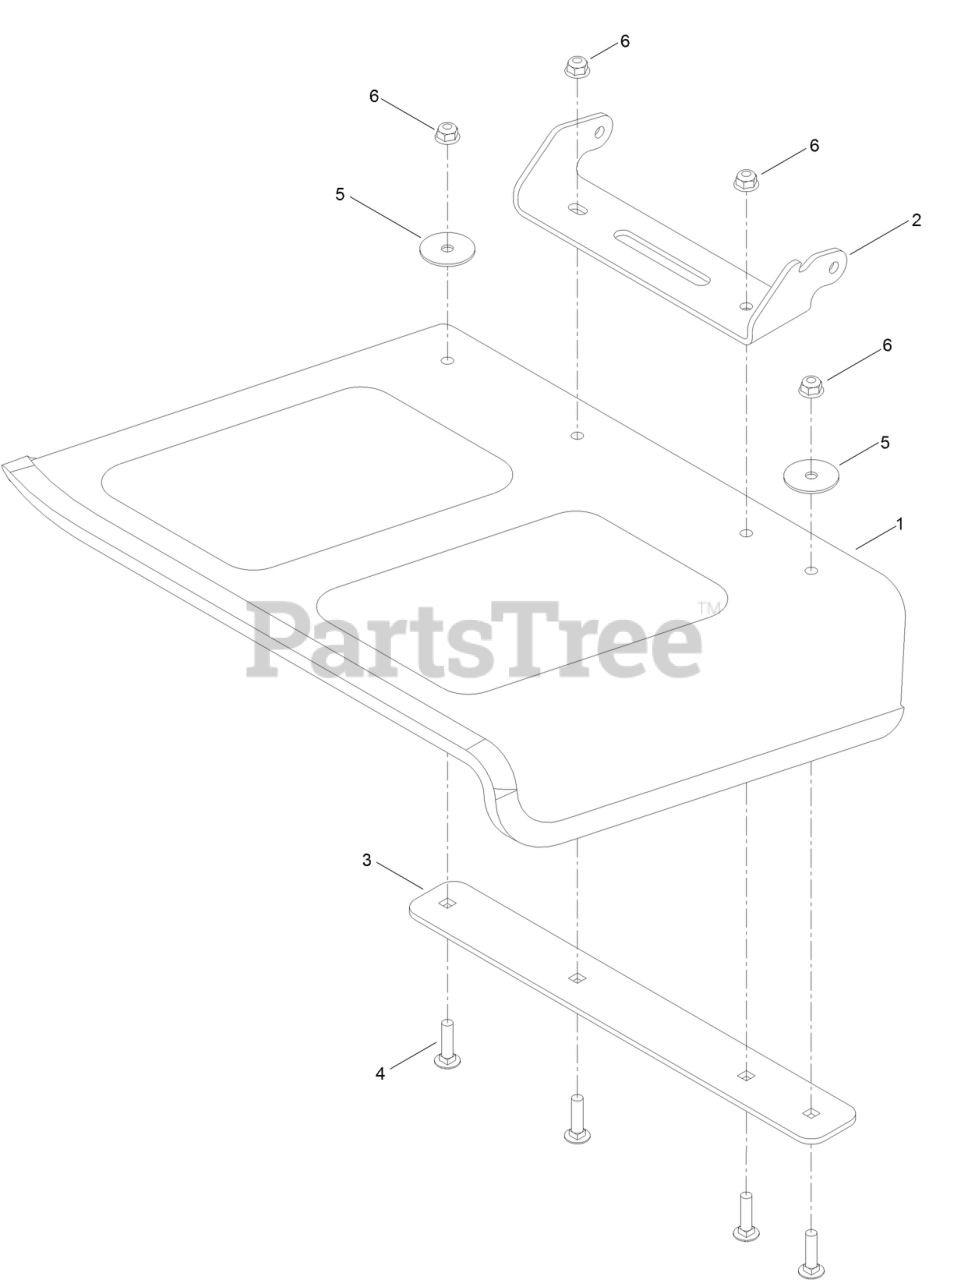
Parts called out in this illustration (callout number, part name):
1	DEFLECTOR
2	BRACKET UPPER, DEFLECTOR
3	PLATE-DEFLECTOR
4	SCREW-CARR
5	WASHER-FLAT
6	NUT-HF, NI
